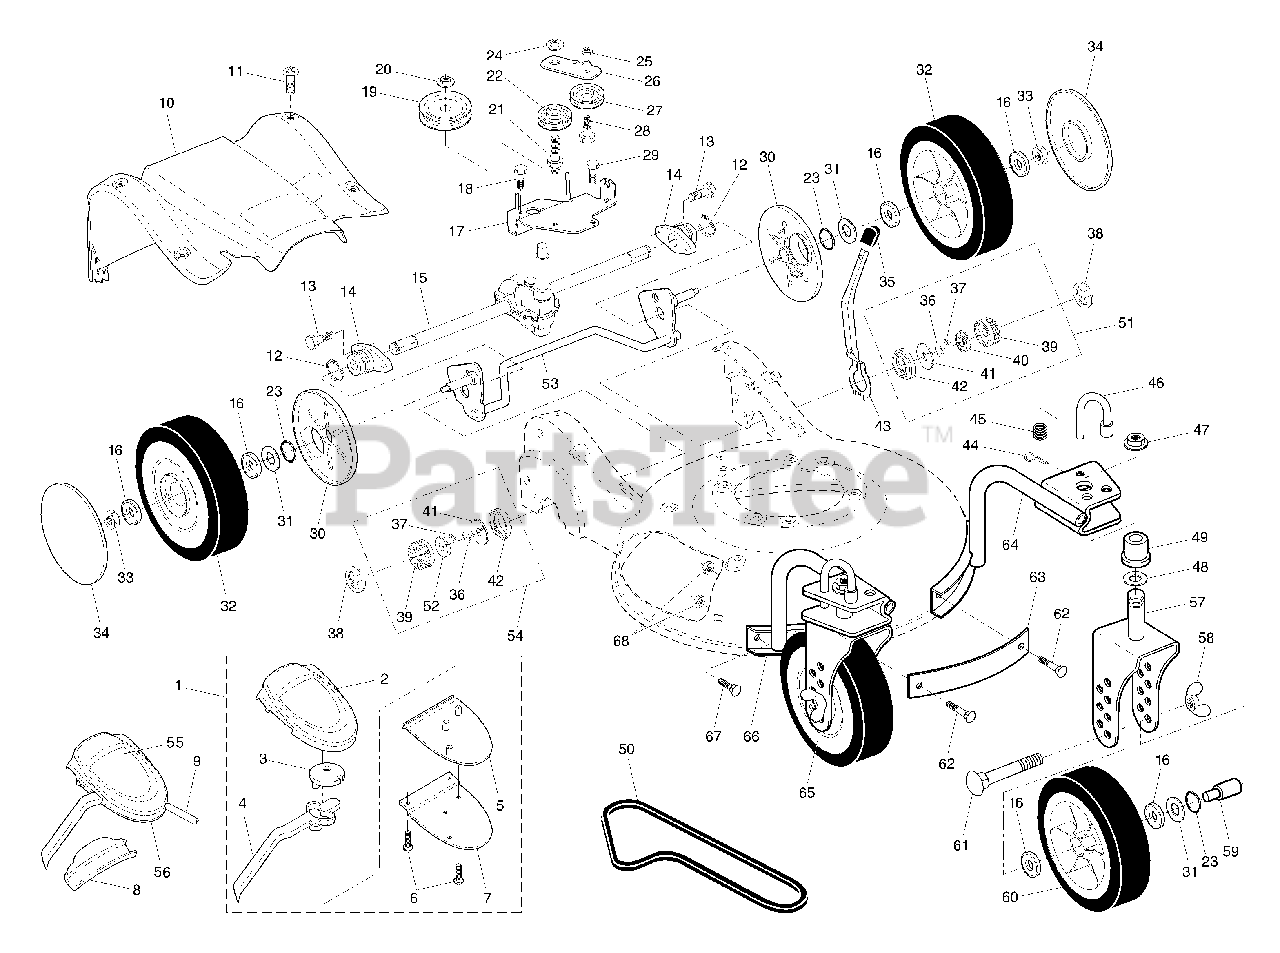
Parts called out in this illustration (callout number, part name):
1	Drive Control Assembly, Complete
2	Cover, Drive Control, Top
3	Pulley, Drive Control
4	Lever, Drive Control (blue)
5	Cover, Drive Control, Bottom
6	Screw, Torx Head #8-5/8
7	Bracket, Mounting, Drive Control
8	Cap, Drive Control, Bottom
9	Cable, Drive Control
10	Cover Assembly, Drive
11	Screw
12	Ring, Retaining
13	Screw
14	Bearing / Axle Support
15	Gear Case Assembly
16	Bearing, Ball (Wheel)
17	Bracket, Gear Case / Drive Pulley
19	Pulley, Drive
20	Nut, Hex, Flangelock
21	Bolt, Idler
22	Pulley Assembly, V-Groove
23	O-Ring
24	Nut, Hex, Flangelock
25	Nut, Hex, Lock
26	Idler Arm
27	Pulley, Idler
28	Bolt, Hex Head, Shoulder
29	Screw 1/4-20 x 1/16
30	Cover, Dust, Wheel
31	Washer, Flat 3/8
32	Wheel Assembly, Rear 9 x 2-1/4
33	Nut, Hex
34	Hubcap
36	Spring, Torsion
40	Retainer, Drive, LH
41	Disc, Drive
42	Seal, Friction
43	Lever, Selector, Wheel Height, Rear
44	Clip, Retainer
47	Nut, Hex, Flangelock
48	Washer, Flat 1/2
49	Bushing
50	Belt, Drive
51	Pinion Assembly, LH
52	Retainer, Drive, RH
53	Rear Axle Assembly
54	Pinion Assembly, RH
55	Decal, Drive Control
56	Decal, Drive Control Adjustment (bottom)
57	Bracket, Caster Wheel, LH
58	Wing Nut 5/16-18
60	Wheel Assembly, Front 9 x 2-1/4
61	Bolt, Carriage 5/16-18 x 3-1/2
62	Bolt, Carriage 5/16-18 x 7/8
63	Strap, Front
64	Support Tube Assembly, LH
65	Bracket, Caster Wheel, RH
66	Support Tube Assembly, RH
67	Bolt, Carriage 5/16-18 x 5/8
68	Nut, Hex 5/16
